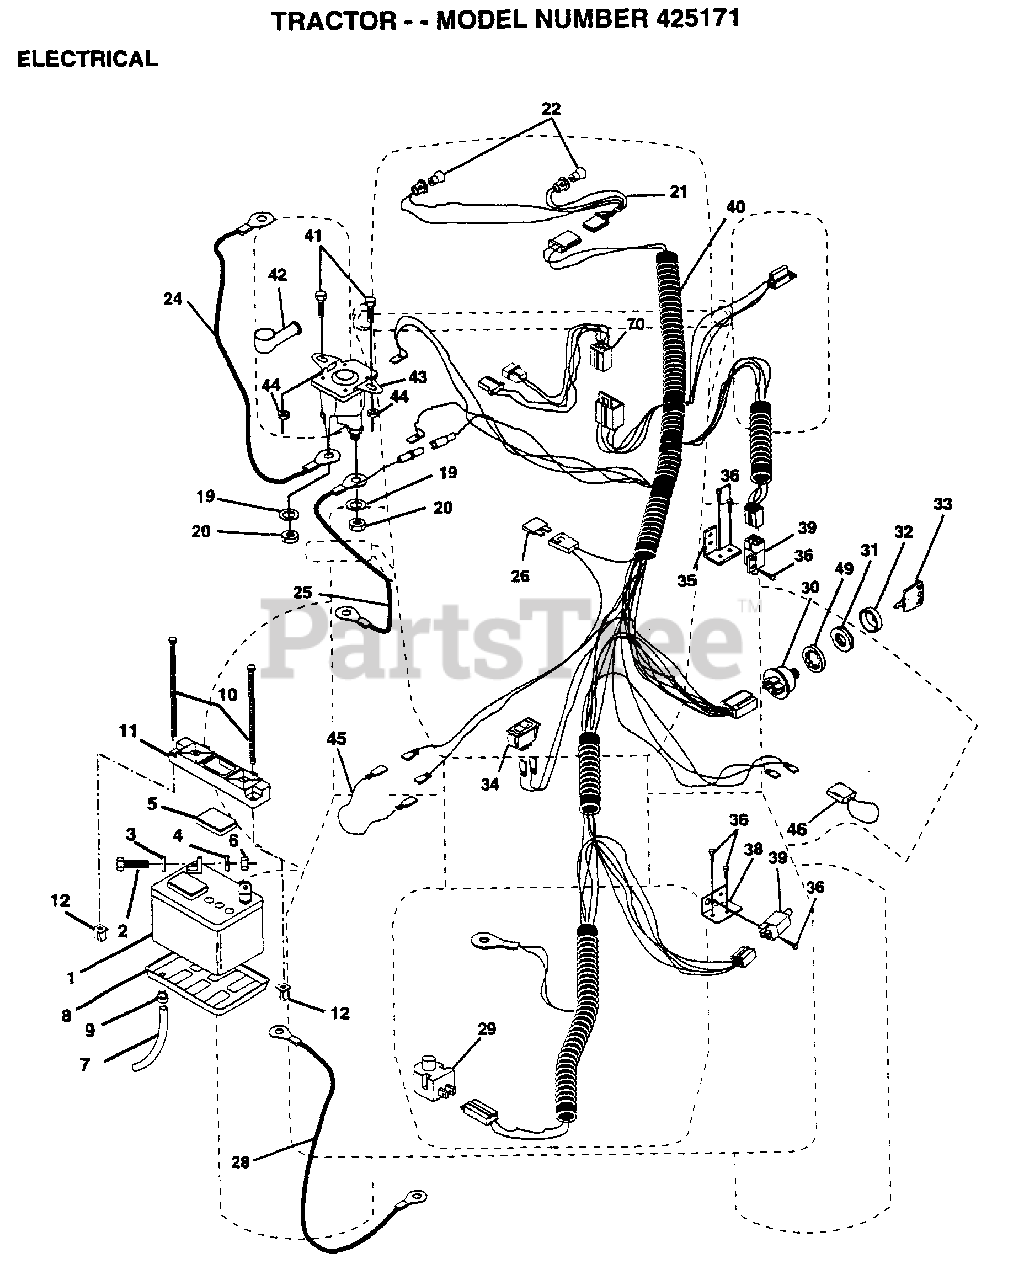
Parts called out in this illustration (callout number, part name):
2	BOLT LT
3	WASHER
4	LOCKWASHER
5	"CAP,BATTERY "
7	"DRAIN TU T, BATT"
8	"TRAY T, BATTERY"
9	HOSE CLAMP T
20	NUT
21	"HARNESS,LIGHT SOC"
22	HEADLAMP BULB
24	"CABLE T, BATTERY"
25	CABLE.6GA.22W/16W
26	FUSE HYT
28	CABLE.GRND.6GA.21
29	SWITCH SEAT
32	COVER KEY SWITCH
33	KEY MLD GEN DELTA
34	SWITCH LT
35	BRACKET LT
36	SCREW
38	BRACKET SWITCH IN
39	SWITCH INTERLOCKT
40	HARNESS.IGN.MECH.
41	BOLT HXHD FIN
44	NUT
45	ADAPTER AMMETER
46	PROTECTION LOOP
47	LOCKWASHER
49	LOCKWASHER
70	HARNESS ENG DUAL
